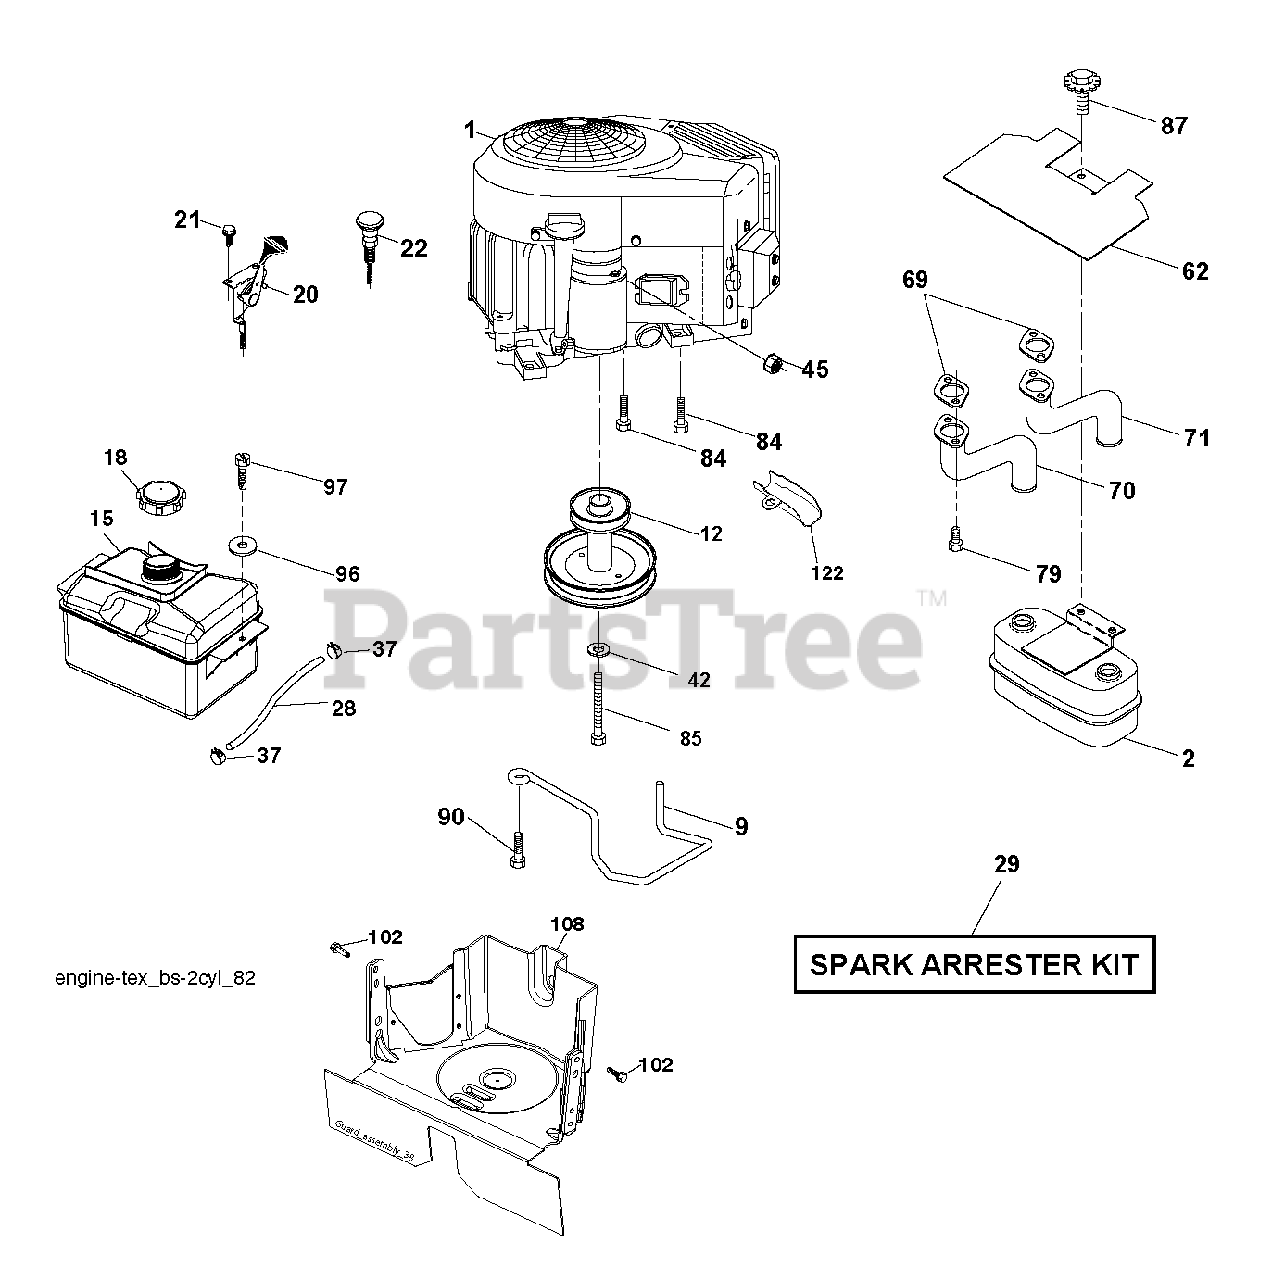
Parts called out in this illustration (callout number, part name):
2	MUFFLER.TWIN.CYL.LOW.TONE
9	KEEPER.BELT.ENGINE.4.2
12	PULLY ENGINE
15	TANK FUEL FRT 1.5 GAL
18	CAP ASM.FUEL.2.25"FR.
20	THROTTLE CABLE
21	SCREW.#10 X 0.750.BOS THREAD
22	CONTROL CHOKE
29	ARRESTER SPARK (OPTIONAL)
42	LOCKWASHER
45	NUT
62	SHIELD.HEAT.MUFFLER
69	REPL BY 532 27 22-93
70	EXHAUST TUBE LH *SUBS/2*
71	EXHAUST TUBE RH
79	SCREW.SOCKET.HEAD.5/16-18
85	BOLT HEX 7/16-20X4-1/4"
87	BOLT, 5/16-18 X 1 3/4
90	SCREW 3/8-16X1
97	SCREW HEXWSHR 1/4-20X3/4
102	SCREW 5/16-18X1
108	COVER PULLEY
122	EXTENSION DRAIN OIL
